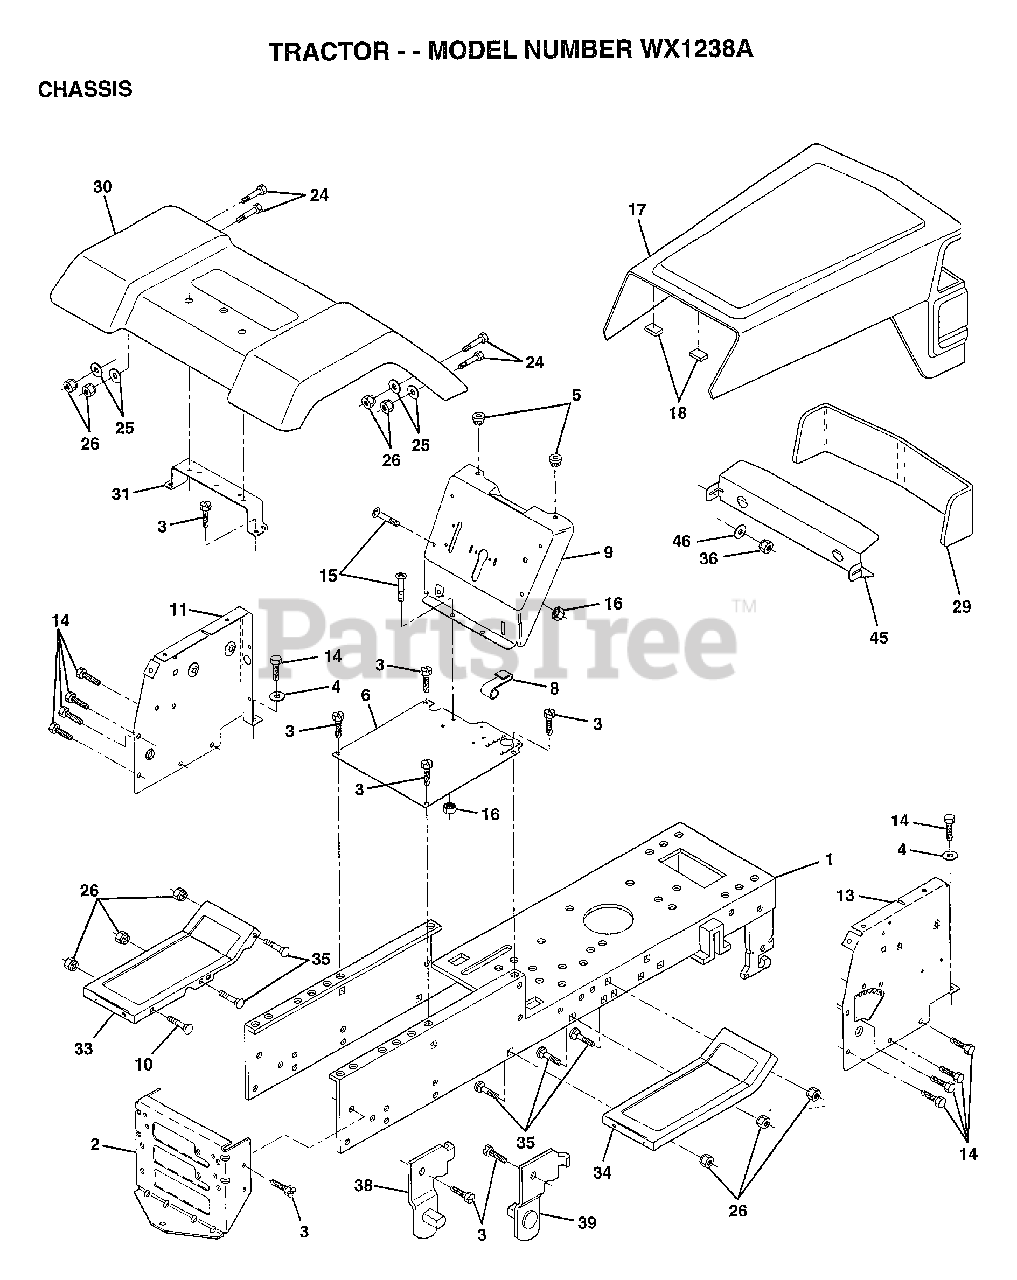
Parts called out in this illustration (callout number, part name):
1	CHASSIS.WLD.11GA
3	SCREW
4	WASHER
8	"CLIP,INSULATOR"
9	DASH.SLKSC.LT.1PC
11	DASH PANEL LH
14	SCREW LT
15	SCREW
17	HOOD/GRILLE.ASM.
24	BOLT
25	WASHER
26	NUT
28	GRILLE.RALLY.BAR.
29	LENS SERVICE KIT
31	BRKT FENDER
33	FOOTREST.LH.PERF.
34	FOOTREST.RH.PERF.
35	BOLT
36	PAL NUT LT
38	BRACKET ASM LH
39	BRACKET ASM RH
46	RETAINER
